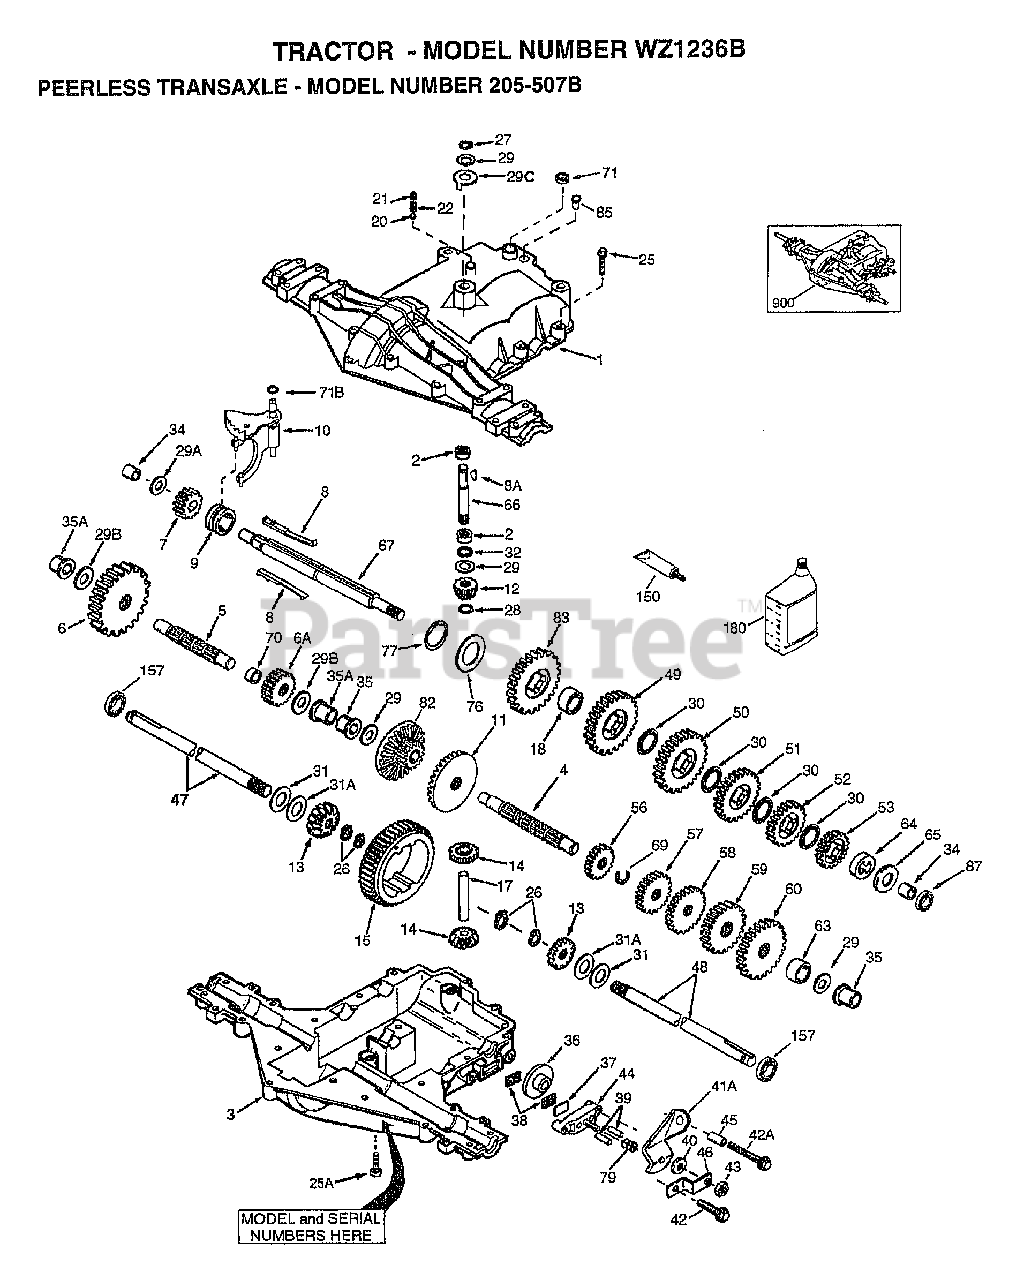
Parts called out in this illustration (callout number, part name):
1	TRANSAXLE COVER
2	NEEDLE BEARING 5/8" ID
3	TRANSAXLE CASE
4	COUNTERSHAFT
5	OUTPUT SHAFT
6	SPUR GEAR (38 TEETH)
6A	SPUR GEAR (15 TEETH)
7	SPUR GEAR (11 TEETH)
8A	KEY, WOODRUFF
9	COLLAR, SHIFTER
10	SHIFT ROD & FORK
11	BEVEL GEAR (30 TEETH)
12	INPUT BEVEL PINION (13TEETH)
13	BEVEL GEAR (13 TEETH)
14	BEVEL PINION (13 TEETH)
15	RING GEAR (43 TEETH)
18	SPACER, NEUTRAL
20	BALL STEEL, 5/16" DIA.
21	SCREW, 3/8-16 X 3/8"
25A	SCREW 1/4-20 X 1-3/8"
26	RING RETAINER
27	RING, RETAINER
28	RETAINING RING
29	WASHER THRUST
29B	WASHER THRUST
29C	P/N CONFLICT - CHECK WITH SUPPLIER
30	WASHER THRUST
31A	FLAT WASHER
32	OIL SEAL 5/8"
34	BUSHING 9/16"
35	FLANGED BUSHING 5/8" ID
35A	FLANGED BUSHING 3/4"
37	PLATE BRAKE PAD
41A	BRAKE LEVER
42A	SCREW, 1/4-20 X 2-1/4
43	LOCKNUT 5/16-24
44	HOLDER BRAKE PAD
46	BRKT BRAKE LEVER
49	SPUR GEAR (29 TEETH)
50	SPUR GEAR (23 TEETH)
51	SPUR GEAR (19 TEETH)
52	SPUR GEAR (16 TEETH)
53	SPUR GEAR (15 TEETH)
56	SPUR GEAR (11 TEETH)
57	SPUR GEAR (17 TEETH)
58	SPUR GEAR (21 TEETH)
59	SPUR GEAR (24 TEETH)
60	SPUR GEAR (25 TEETH)
66	INPUT SHAFT
67	SHIFTER & BRAKE SHAFT
69	RETAINING RING
70	SPACER .890
71	SEAL SQUARE CUT
76	WASHER, THRUST
77	INVERTED RETAINING RING
82	BEVEL & SPUR GEAR (30 & 13 TEETH)
83	SPUR GEAR (27 TEETH)
85	OIL FILL PLUG
87	OIL SEAL 9/16"
150	LIQUID GASKET RTV SILICONE
157	OIL SEAL 3/4"
180	GEAR OIL 80W90
